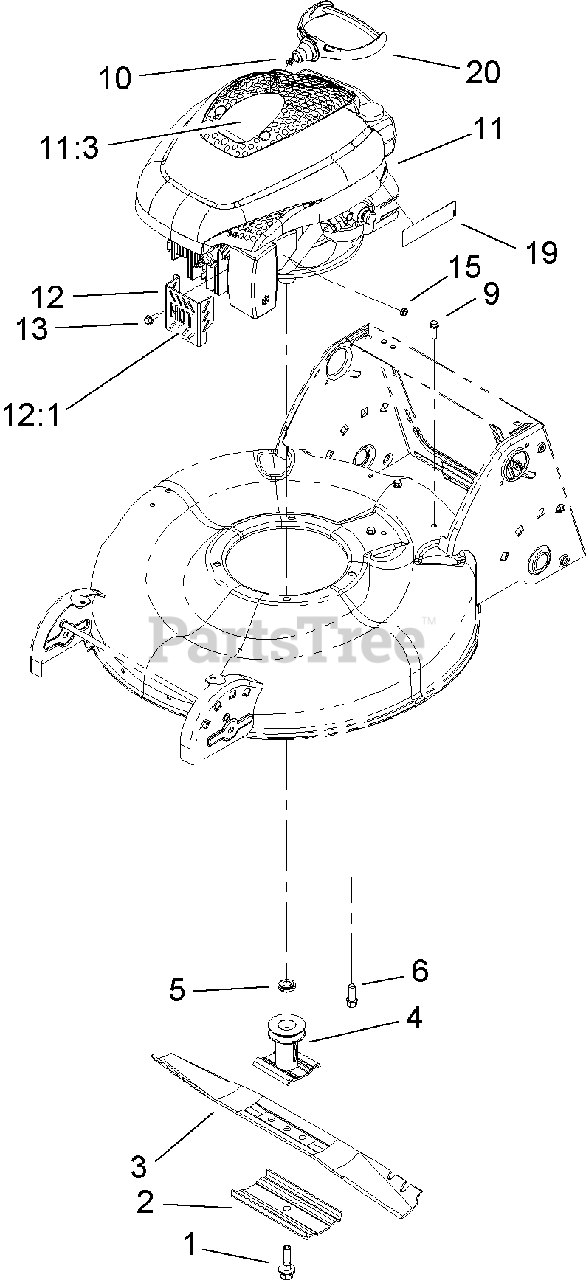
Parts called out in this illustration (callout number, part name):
1	BOLT-BLADE
2	SUPPORT-BLADE
3	BLADE-21 IN
4	BLADE DRIVER ASM
5	Spacer-Driver
6	SCREW
9	SCREW-HWH
10	STOP-ROPE
11:3	DECAL-RECOIL
12	MUFFLER GUARD ASM
12:1	DECAL-SURFACE, HOT
13	SCREW-HWH
15	NUT-KEPS
19	DECAL-PRIMER
20	HANDLE-RECOIL
